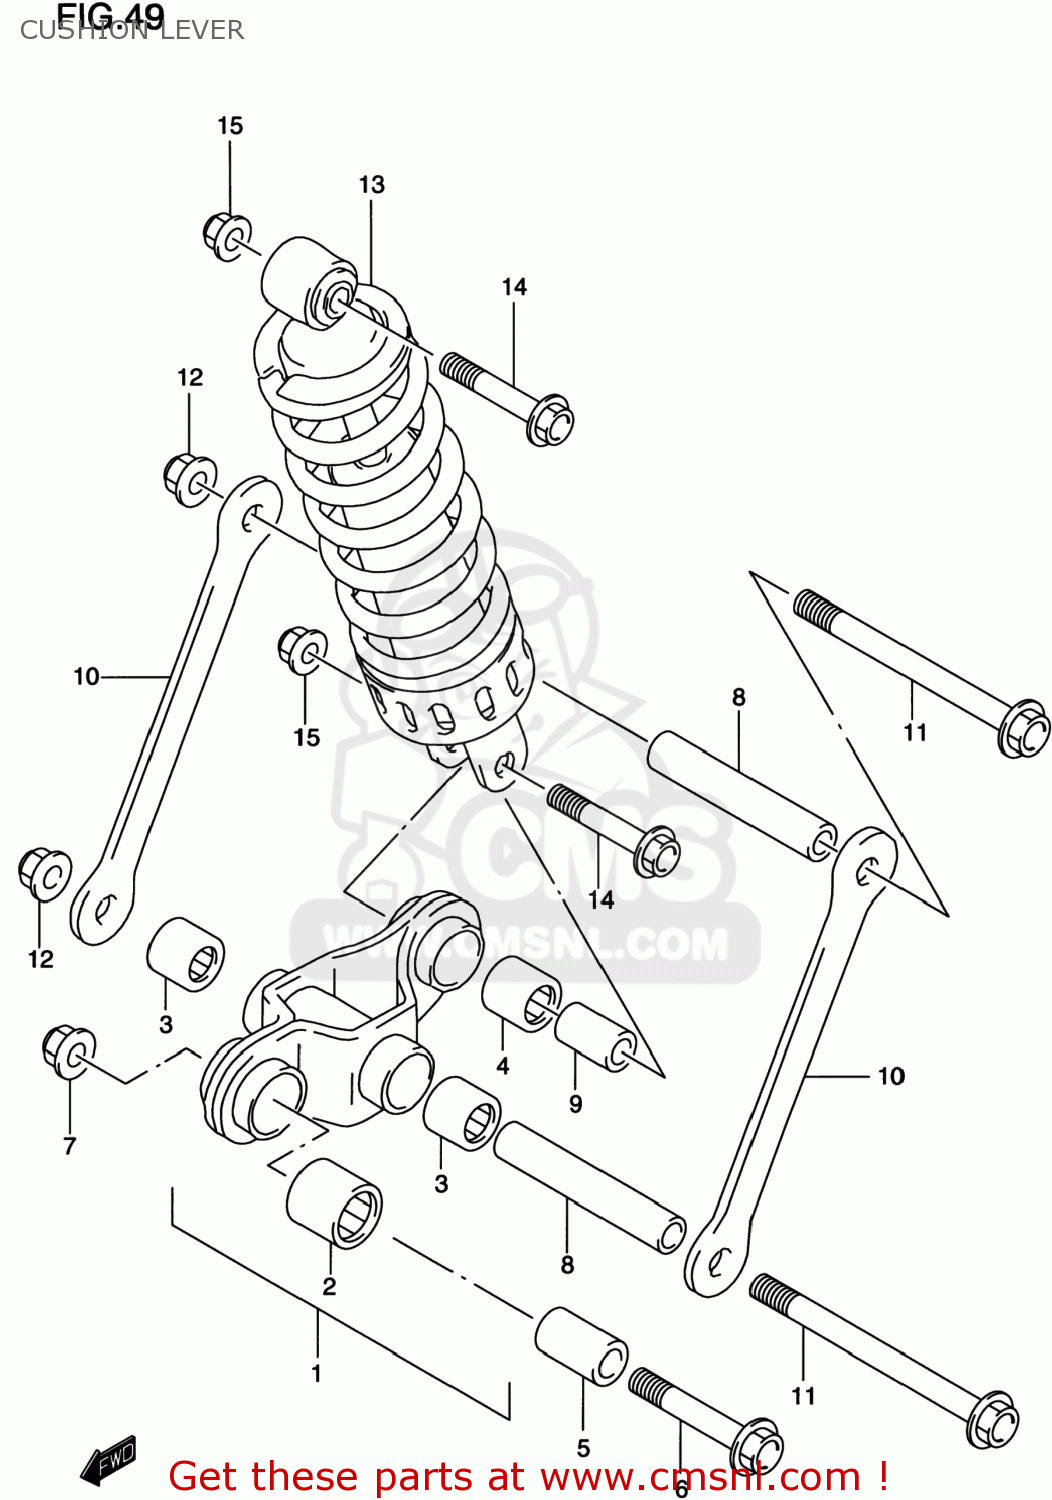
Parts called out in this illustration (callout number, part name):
1	LEVER SET,RR CUSHION
2	BEARING(20X27X26)
3	BEARING(17X24X25)
4	BEARING(17X24X26)
5	SPACER,RR CUSHION LEVER FR
6	BOLT(12X57)
7	NUT 12MM
8	SPACER (12X17X89)
9	SPACER,RR CUSHION LEVER
10	ROD,RR CUSHION LEVER
11	BOLT(12X118)
12	NUT 12MM
13	ABSORBER ASSY,RR SHOCK
14	BOLT(10X52)
15	NUT
